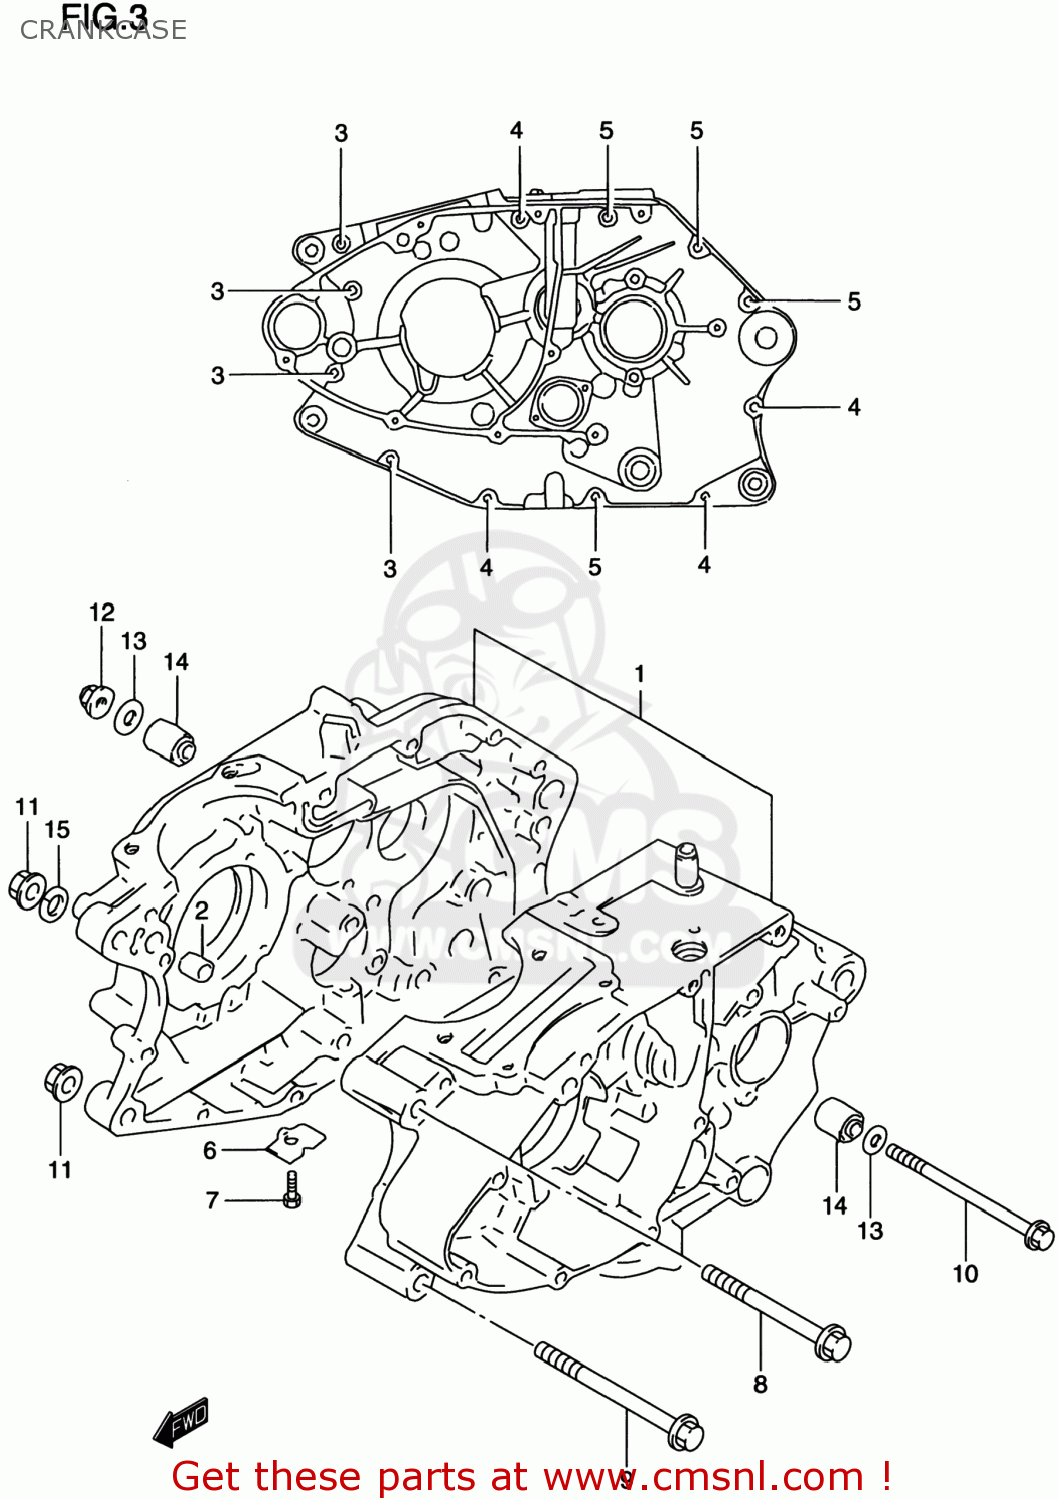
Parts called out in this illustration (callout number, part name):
1	CRANKCASE ASSEMBLY
2	PIN
3	BOLT
4	BOLT
5	BOLT
6	PLATE,OIL GALLERY PLUG
7	BOLT
8	BOLT(10X80)
9	BOLT(10X90)
10	BOLT(8X115)
11	NUT
12	NUT
13	WASHER
14	BUSH(8.4X18X16)
15	WASHER
